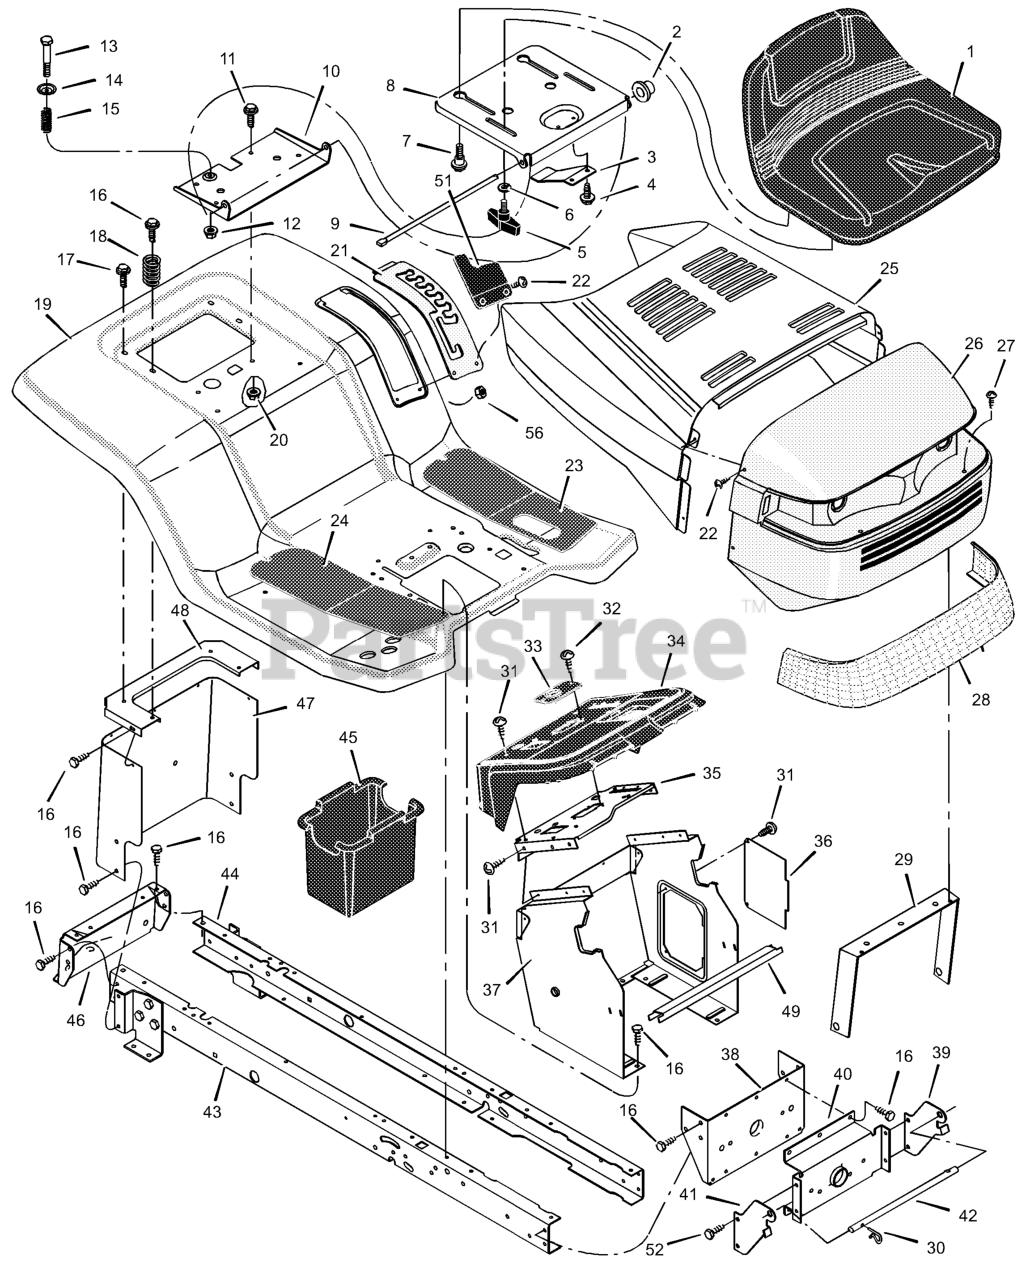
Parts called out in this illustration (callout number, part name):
1	Seat
2	Cap, Push On
5	Bolt, Wing
6	Washer
7	Bolt, Shoulder
8	Support, Seat
9	Rod, Pivot
10	Bracket, Pivot
11	Bolt
13	Bolt, Shoulder
15	Spring
19	Deck, Seat
20	Nut
21	Plate, Index
23	Mat, Left
24	Mat, Right
25	Hood
26	Grille Assembly
27	Screw
29	Brace, Grille
30	Pin, Hair
31	Screw
33	Bearing, Steering
35	Plate, Dash
36	Panel, Access
37	Support, Dash
38	Bracket, Rear Hanger
39	Support, Left Grille
40	Axle, Hanger
41	Support, Right Grille
42	Rod, Pivot
43	Frame, Right
44	Frame, Left
45	Container, Battery
46	Plate, Hitch
47	Plate, Rear
48	Top, Rear Plate
51	Cover, Detent
56	Locknut
